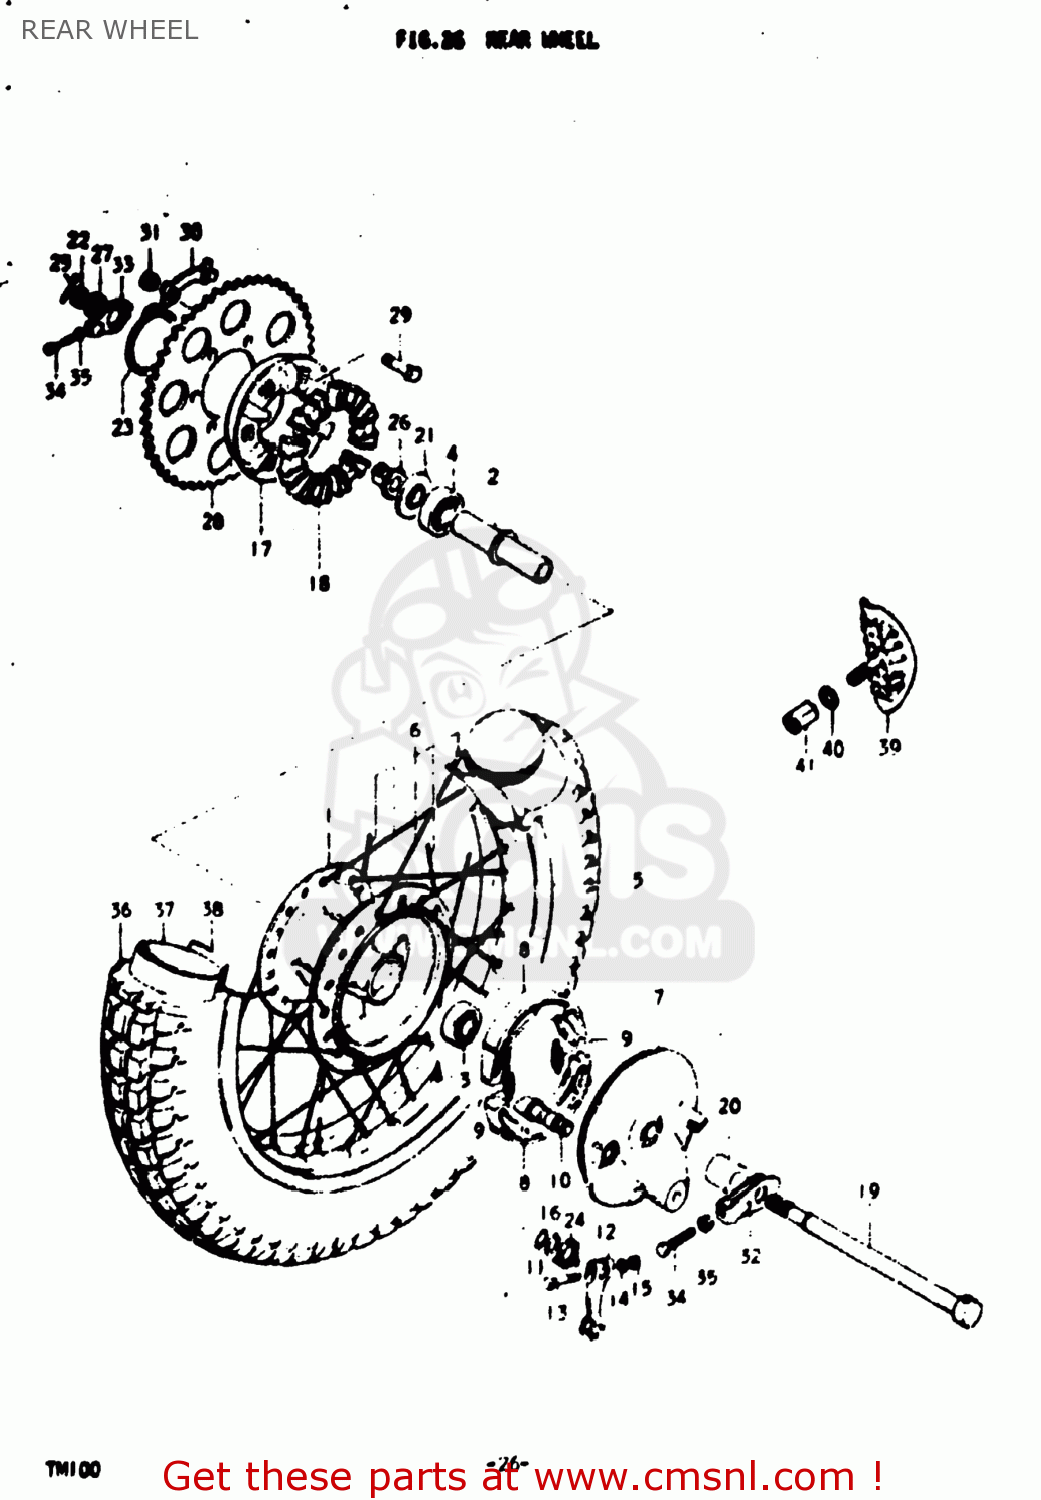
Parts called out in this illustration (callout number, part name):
0	HUB SET,REAR
1	HUB,REAR
2	SPACER,REAR HUB BEARING
3	BEARING
4	BEARING
5	RIM,REAR WHEEL
6	SPOKE SET,REAR
7	PANEL,REAR HUB
8	SHOE,BRAKE
9	SPRING(L:34)
10	CAM,FR BRAKE
11	O RING(D:2.5,ID:11.4)
12	LEVER,REAR BRAKE CAM
13	BOLT
14	WASHER
15	NUT
16	WASHER(12.5X20X1)
17	DRUM,REAR SPROCKET MOUNT
18	CUSHION,REAR DRUM
19	AXLE,REAR
20	SPACER
21	SPACER,RR AXLE,L
22	NUT 12MM
23	CIRCLIP
24	SPRING
25	COTTER PIN
26	SPACER,CHAIN ADJUSTER,L
27	NUT
28	SPROCKET,REAR
29	BOLT(8X32)
30	WASHER
31	NUT
32	ADJUSTER,CHAIN
33	ADJUSTER,CHAIN
34	BOLT
35	NUT
36	TIRE
37	TUBE ASSEMBLY,WHEEL,INNER
38	PROTECTOR,WHEEL,INNER
39	STOPPER,BEAD
40	WASHER
41	NUT
